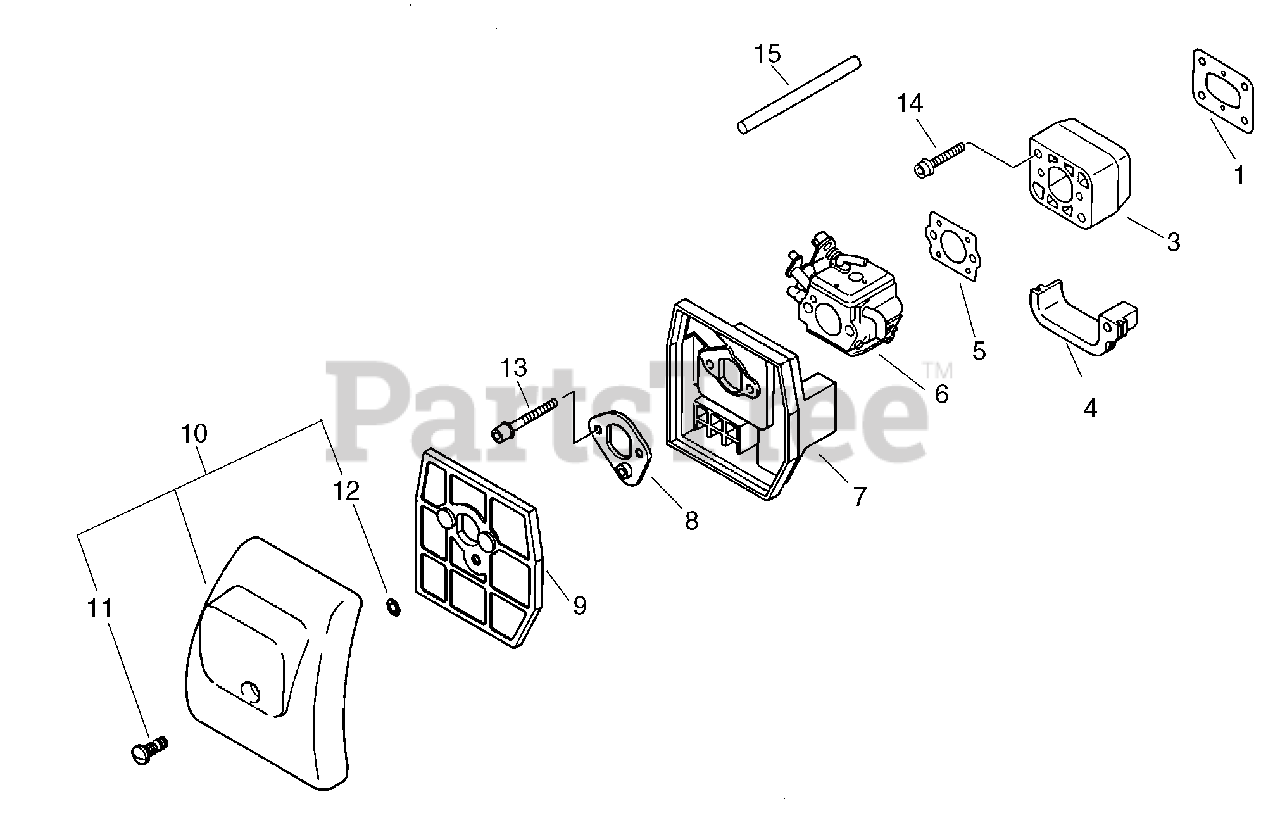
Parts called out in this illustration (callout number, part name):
1	GASKET, INTAKE
3	INSULATOR
5	GASKET, INTAKE
6	CARBURETOR
7	CASE, AIR FILTER
8	BRACKET, AIR CLEANER
9	FILTER, AIR
10	AIR FILTER COVER ASSY
12	O-RING - 4
13	SCREW - 5X55
14	SCREW - 5X30
15	PIPE - 3X6X105 -- BLACK
